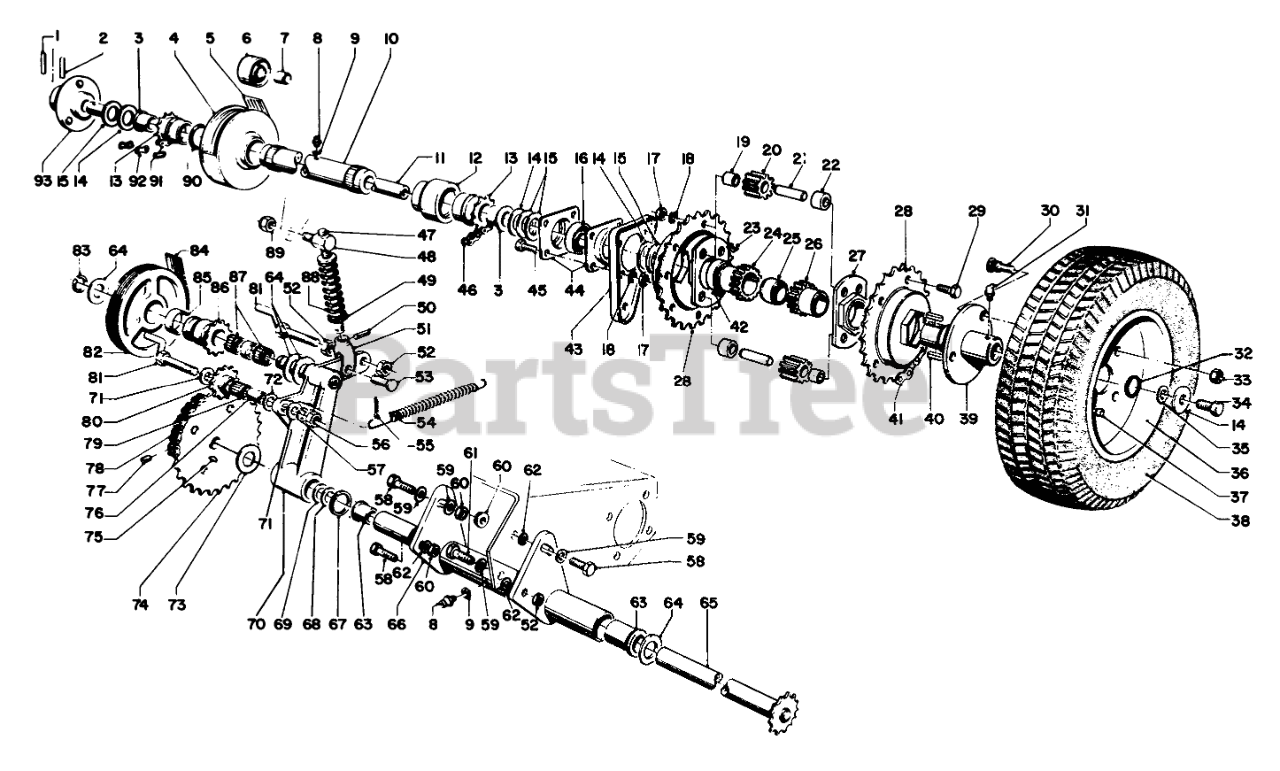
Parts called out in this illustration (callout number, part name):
1	PIN-ROLL
2	PIN-ROLL, SLOTTED
3	3/4IDX1LG FLANGE BSHG
4	Pulley & Hub Assembly (Incl. Ref. #90)
5	REEL BELT
6	REEL IDLER R
7	TOL RING
8	FITTING-GREASE
9	WASHER-LOCK
10	REEL DRIVE TUBE R
13	Sprocket (Incl. Ref. #3)
14	THRUST WASHER
15	WASHER-THRUST
16	Bearing
17	NUT-HEX
18	WASHER-LOCK
19	BUSHING
20	Gear-Spur (Incl. Ref. #19)
21	GEAR BUSHING SHAFT
22	SPACER
23	KEY-WOODRUFF
24	Side Gear, Differential
25	SPACER
26	Side Gear, Differential
27	Planet Carrier (Incl. Ref. #42)
28	Case, Sprocket
29	SCREW-HH
30	DRIVE STUD
31	FITTING-LUBE, 45 DEG
32	O-RING
33	LUG NUT
34	SCREW-HH
35	WASHER-LOCK
36	Wheel Disc Assy.
37	STEM-VALVE
38	Tire
39	Hub, Left Side (Incl. Ref. #30)
40	KEY-SQUARE
41	Chain
42	Bushing
43	Bracket
44	Bearing Retainer
45	SCREW-HH
46	Chain, Reel Drive-Rear
47	ROD & FLANGE WA
48	Pivot Rod
49	WASHER-FLAT
50	PIN-ROLL, SLOTTED
51	CLEVIS
52	NUT-JAM
53	PIN-CLEVIS
54	SPRING-EXTENSION
55	PIN-COTTER
56	NUT-HEX
57	WASHER-LOCK
58	SCREW-HH
59	WASHER-FLAT
60	NUT-KEPS
61	SCREW-HH
62	WASHER-LOCK
63	Bushing
64	THRUST WASHER
65	Countershaft & Sprocket
66	Countershaft Tube Assembly (Incl. Ref. #63)
67	RING-SNAP
68	THRUST WASHER
69	THRUST WASHER
70	Belt Crank Assy. (Incl. Ref. #8)
71	WASHER-PLAIN
72	WASHER-FLAT
73	THRUST WASHER
74	LARGE SPROCKET ASM
75	KEY-WOODRUFF
76	SPINDLE
77	SCREW-SET
78	TRACTION CHAIN
79	Bearing
80	Sprocket, Idler (Incl. Ref. #79)
81	Belt Guide
82	TRACTION PULLEY
83	5/8X030 EX MED RING
84	TRACTION BELT
85	Ring Tolerance
86	TRACTION SPROCKET
87	.625 NEEDLE BEARING
88	COMP SPRING R
89	NUT-LOCK, NI
90	2-1/2X086 EX SNP RING
91	Chain, Reel Drive-Front
92	LINK-CONNECTING
93	Hub Right Side (Incl. Ref. #30)
